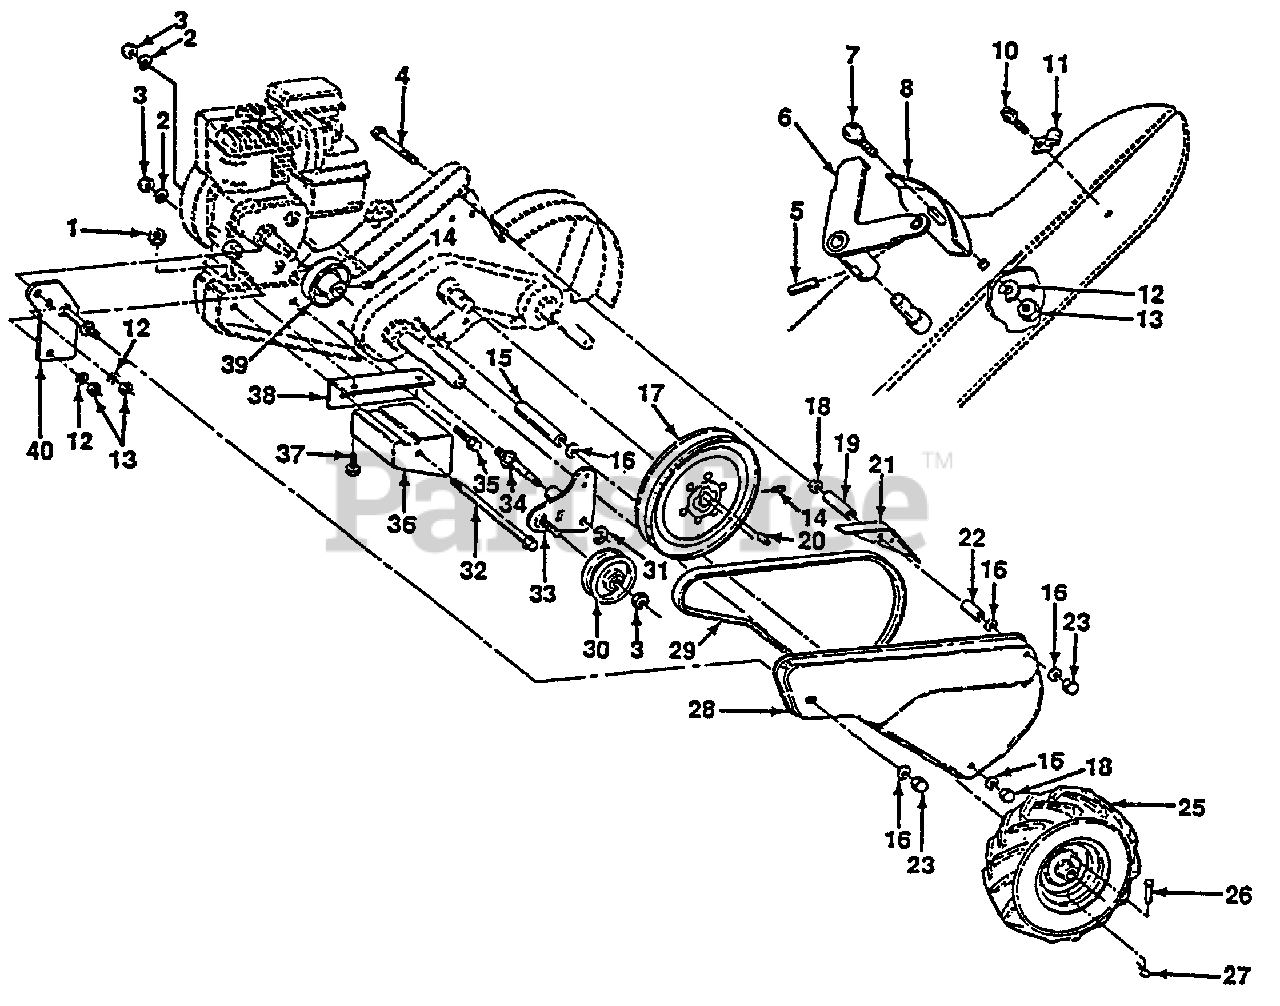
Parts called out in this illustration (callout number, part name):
1	Nut, Keps 5/16-18
2	Washer, Lock 3/8
3	Nut, Hex 3/8-16
4	Bolt, Hex 5/16-18 x 4-3/4
5	Pin, Roll
6	Lever, Shift
7	Bolt, Carriage 1/4-20 x 1/2 Gr. 5
8	Panel, Shift Indicator
10	Screw, Hex, Washer Head, Slotted #10-24 x 1/2
12	Washer, Lock 1/4
13	Nut, Hex 1/4-20
14	Screw, Set Hex 5/16-18 x 3/8
15	Spacer, Split 0.327 x 0.42 x 2.68
16	Washer 11/32 x 11/16 x 16 Ga.
17	Sheave, Transmission
18	Nut, Hex 5/16-18
19	Spacer, Split 0.327 x 0.42 x 1.75
20	Key, Square 3/16 x 1-1/8
21	Guard, Pinch Point
22	Spacer, Split 0.327 x 0.42 x 2.09
23	Nut, Cap 5/16-18
25	Tire Valve
26	Rivet, Drilled
27	Clip, Hairpin
28	Guard, Belt
29	Belt, V
30	Pulley, idler
31	Ring, Klip
32	Bolt, Hex 5/16-16 x 12
33	Bracket, Idler
34	Shaft, Idler Arm
35	Bolt, Hex 3/8-16 x 1
36	Counterweight, L. H.
37	Bolt, Hex 5/16-18 x 1-1/2
38	Bracket, Reinforcement, L. H.
39	Sheave, Engine
40	Bracket, Guard Belt
